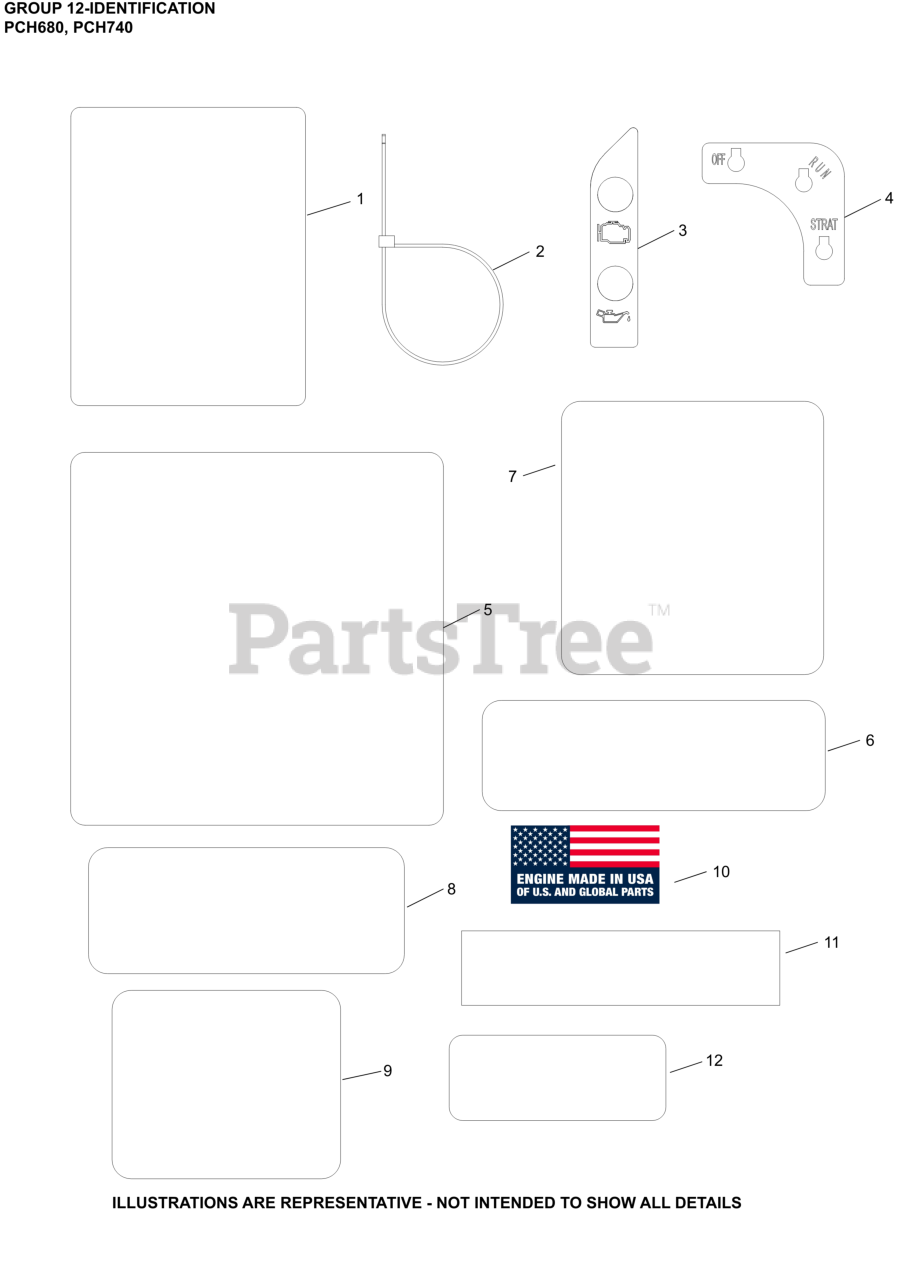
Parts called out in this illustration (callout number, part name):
1	LABEL, CLEAR LAMINATION
3	DECAL, WARNING LIGHT
6	DECAL LPAC, 25 HP/747cc/PCH740
8	DECAL, SYNTHETIC OIL
10	DECAL, USA
NI	LABEL, GRASS SCREEN
